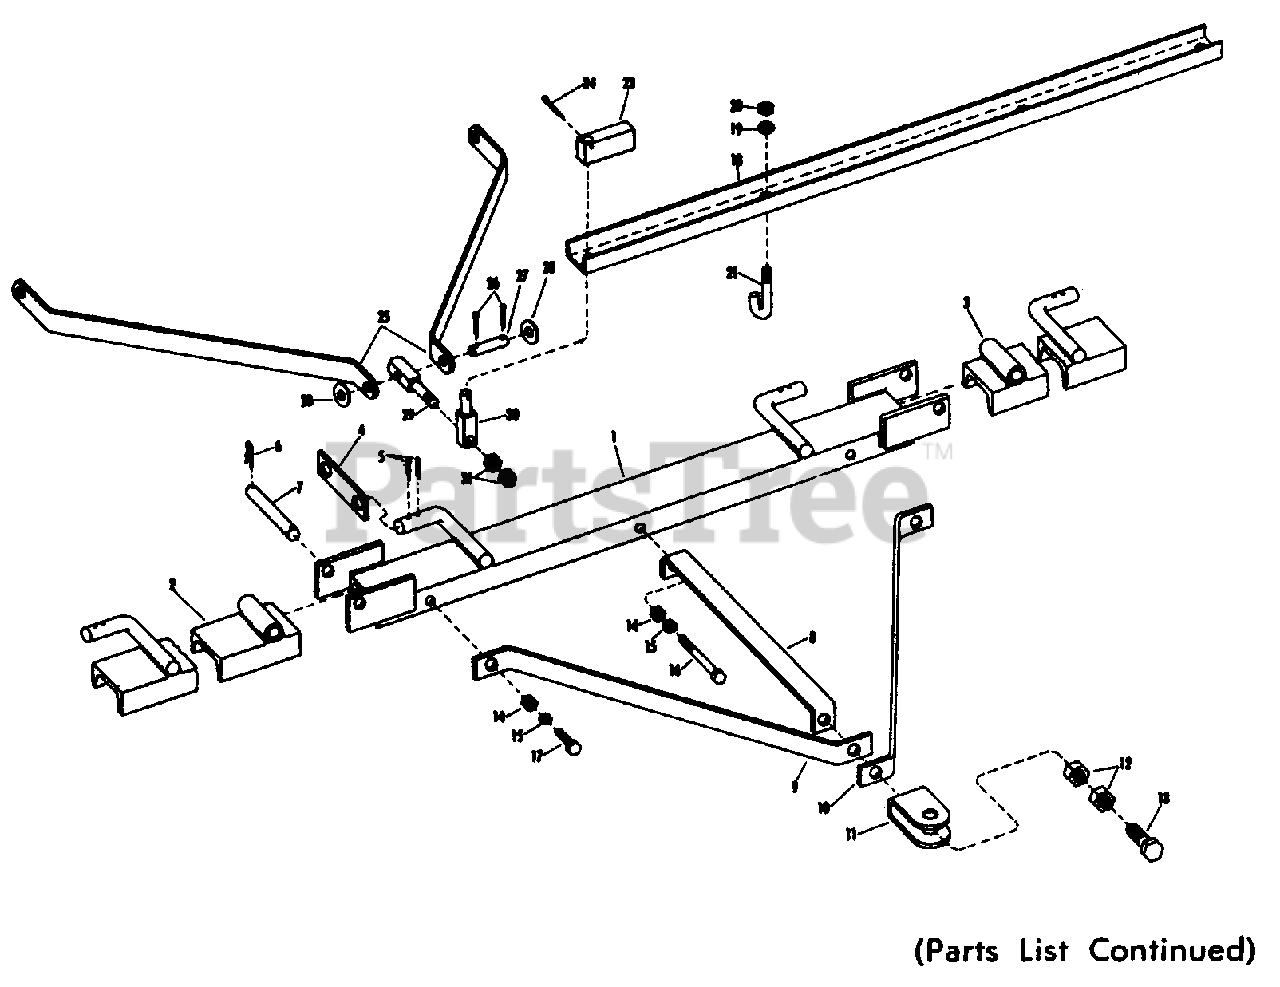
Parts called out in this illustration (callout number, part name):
1	Front Draw Bar w/Spindles-Center
2	Front Draw Bar w/Spindles-RH Side
3	Front Draw Bar w/Spindles-LH Side
4	Connecting Link-Spindle
5	Cotter Pin
6	Hair Pin Cotter for Channel Pivot Pin
7	Pin, Channel Pivot
8	Tie Iron, Center, Front Hitch
9	Tie Iron, RH, Front Hitch
10	Tie Iron, LH, Front Hitch
11	Swivel Hitch, Front
13	Cap Screw
15	Lock Washer
16	Cap Screw
17	Cap Screw
18	Rear Draw Bar
19	Lock Washer
21	J Bolt for Draw Bar
23	Swivel Stop
24	Cotter Pin, 3/16" x 1-1/4" lg.
25	Tie Iron, R. or L.
26	Cotter Pins
27	Pin for Swivel Shafts and Tie Irons
28	Flat Washer
29	Tie Irons
30	Shaft, Swivel Hitch
31	Hex Nut, 1/2"-13
